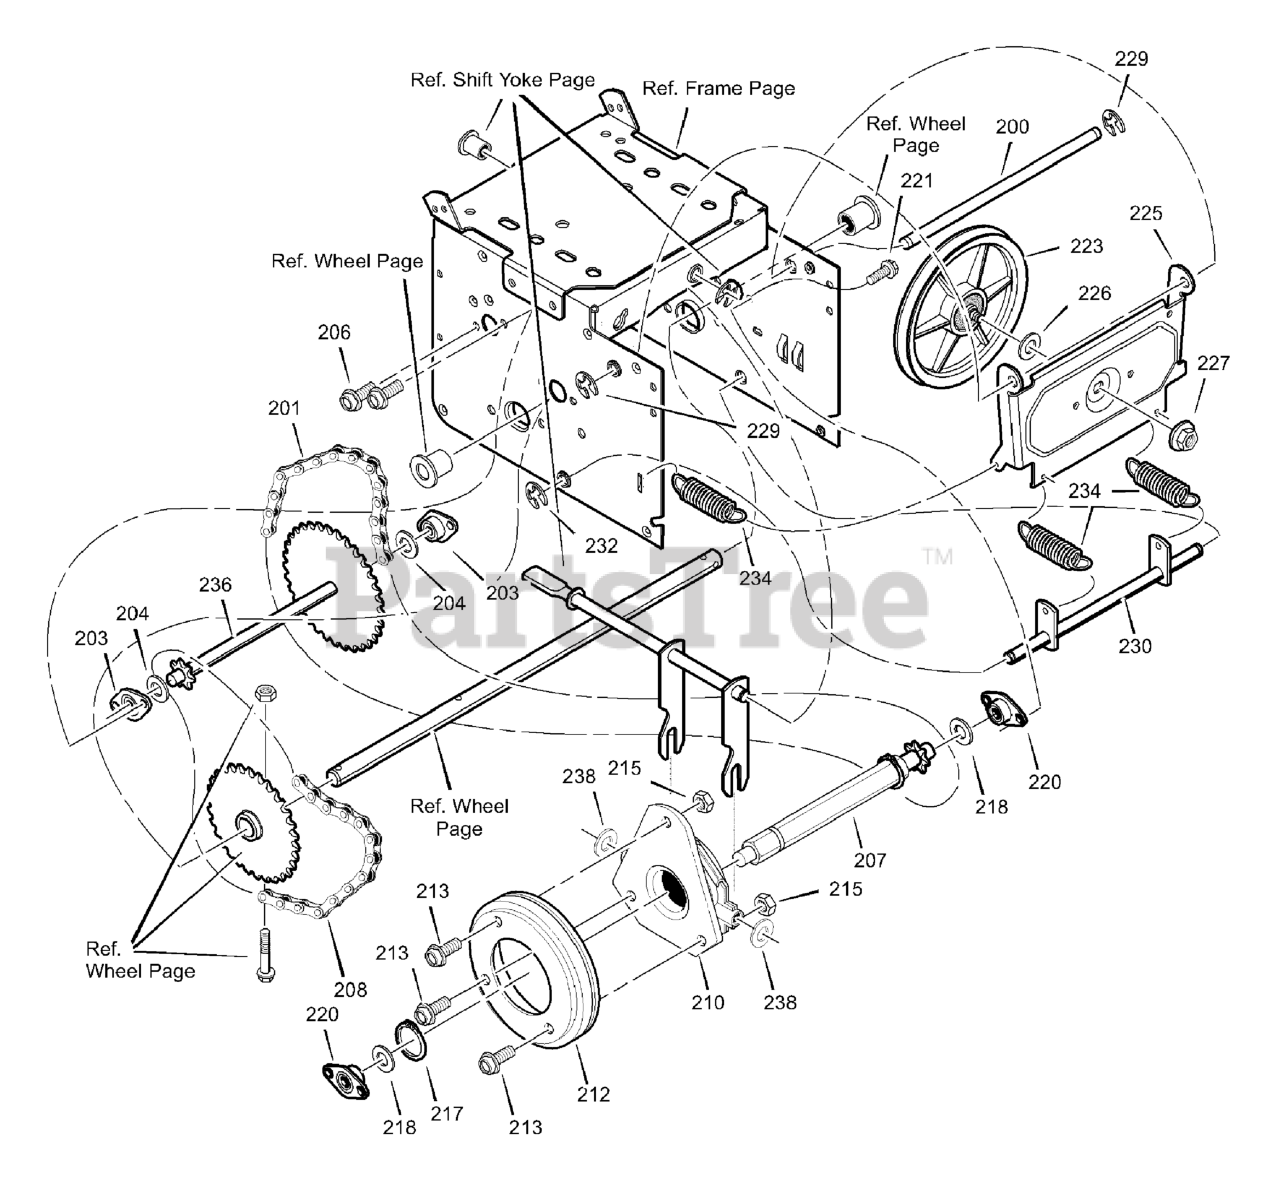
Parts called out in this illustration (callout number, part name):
200	LF AXLE, SWING PLATE YZ
201	CHAIN, ROLLER #420x19.00
203	BEARING AND RETAINER, ASSY
206	SCREW, TAP 5/16-18 x 0.5
207	ASSY, HEX SHAFT
208	CHAIN, ROLLER 420x18.00 LG
210	BEARING, TRUNION CLUTCH R
212	WHEEL, FRICTION DISC
215	NUT, KEPS HEX 1/4-20
217	RING, RETEXT
220	BEARING AND RETAINER, ASSY
221	SCREW, TAP 5/16-18 X .50
223	ASSY, FRICTION PULLEY
225	LF PLATE, SWINGING YZ
226	SPACER, FRICTION PULLEY
227	NUT, FLANGE LOCK 3/8-24
229	RETAINER, RING
230	LF ASSY, SPRING LINK YZ
232	RETAINER, RING
234	SPRING, EXTENSION
236	WLD, INTERMED SPROCKET 33T/7
238	WASHER, FLAT
